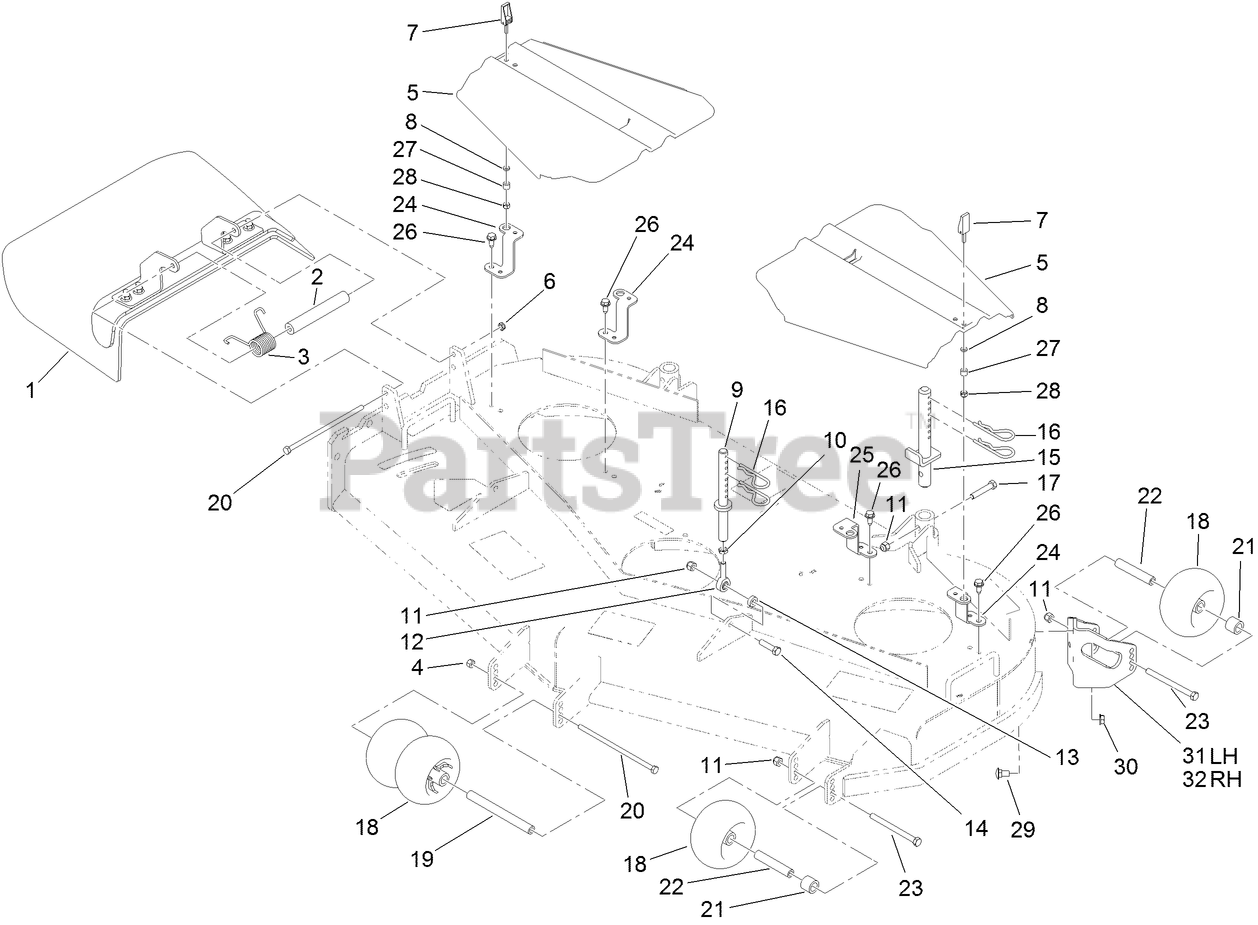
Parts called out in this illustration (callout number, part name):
1	DEFLECTOR ASM
2	SPACER
3	SPRING-TORSION
4	NUT-LOCK, NI
5	COVER-BELT
6	NUT-LOCK, NI
7	HANDLE-LATCH, SWELL
8	WASHER
9	FRONT PIN ASM
10	NUT-HJ
11	NUT-LOCK, NI
12	BALLJOINT
13	SPACER
14	SCREW-HH
15	REAR PIN ASM
16	PIN-HAIR
17	SCREW-HH
18	ROLLER-SCALP, ANTI
19	SPACER-WHEEL
20	SCREW-HH
21	TUBE-SPACER
22	TUBE-SPANNER
23	SCREW-HH
24	BRACKET-COVER
25	BRACKET-COVER
26	SCREW-HWHTF
27	BUSHING-LATCH, SWELL
28	NUT-LOCK, HH
29	SCREW-CARR
30	NUT-HF
31	BRACKET-ROLLER, LH
32	BRACKET-ROLLER, RH
